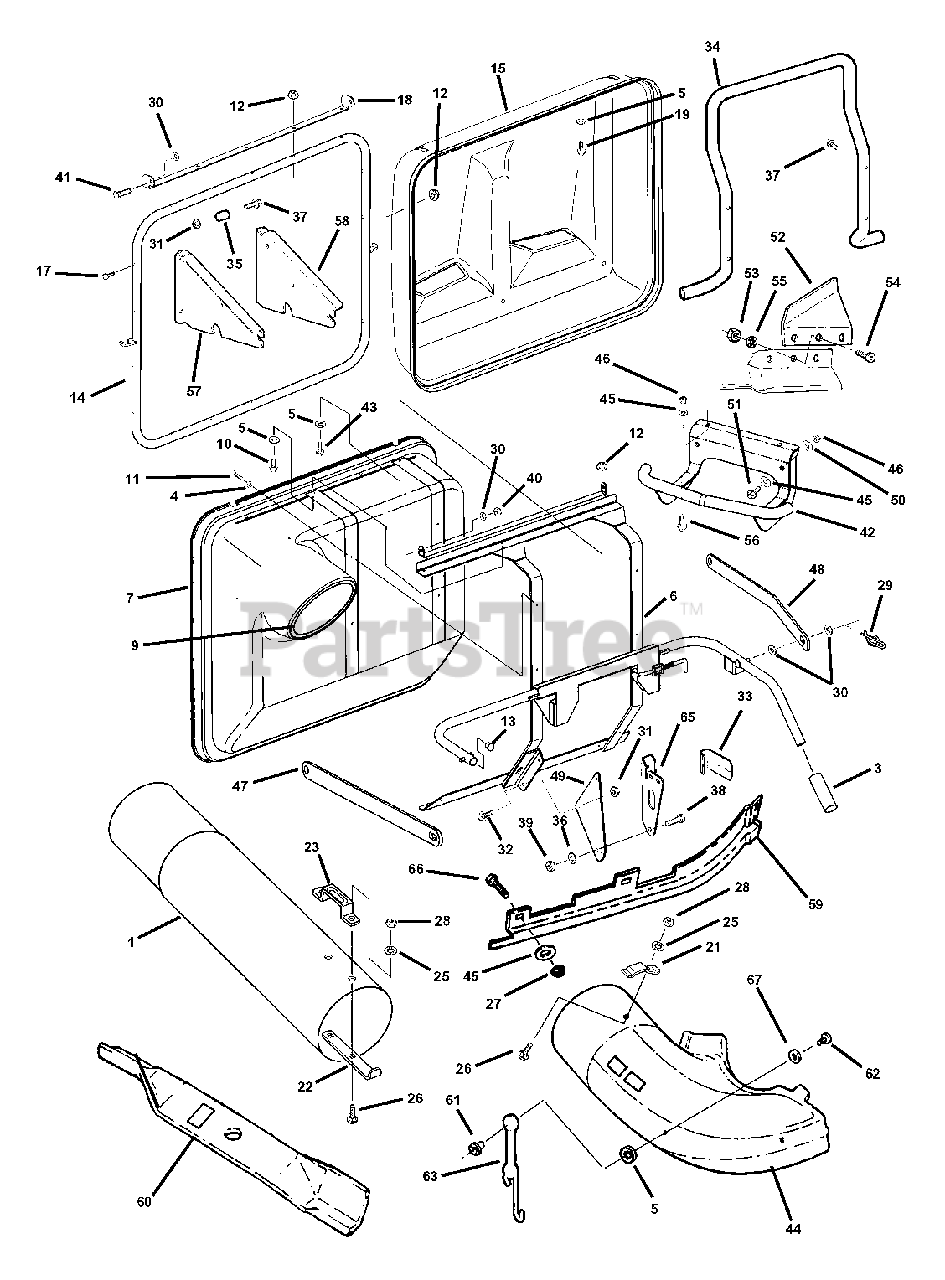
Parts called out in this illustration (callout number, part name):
1	TUBE, Grass
3	GRIP
4	WASHER, 11/32 Flat
5	WASHER, 3/16 Flat
6	WELDMENT, Front Cover Brace
7	COVER, Front
9	GASKET, Chute
10	SCREW, #10-24 x 1/2" Hex Washer Self-Tap (Torx)
11	SCREW, 1/4-20 x 5/8" Pan Head Self-Tapping
12	NUT, #10-24 Hex Fl. Lock
13	END CAP, Tube
14	WELDMENT, Rear Cover Brace
15	COVER, Rear
17	BOLT, #10-24 x 1-1/2" Oval Head
18	HINGE, Rear Cover
19	SCREW, #10-24 x 1-1/2 Machine
21	LATCH, Chute/Tube
22	BASE, Handle
23	HANDLE, Tube
25	WASHER, 1/4 Internal Tooth Lock
26	BOLT, 1/4-20 x 3/4" Round Hd. Short Nk. Carriage, Gr. 5
27	NUT, 5/16-18 Hex Ctr. Lock
28	NUT, 1/4-20 Hex
29	PIN, 3/8 Self Lock Cotter
30	WASHER, 3/8" Flat
31	NUT, 5/16-18 Flange Lock
32	BOLT, 5/16-18 x 5/8" Hex Flange Lock
33	SUPPORT, Bumper
34	BUMPER, Rear
35	SPACER, Bumper Bracket
36	WASHER, 1/2 Internal Tooth Lock
37	SCREW, 5/16-18 x 1-3/4" Hex Washer Self-Tapping
38	BOLT, 1/2-13 x 1" Hex Head Cap Grade 5
39	NUT, 1/2-13 Hex Grade B
40	NUT, 3/8-16 Hex Lock
41	SCREW, 3/8-16 x 1" Hex Head Cap, Grade 5
42	WELDMENT, LT Bumper
43	BOLT, #10-24 x 3/4" Hex Flange Lock, Grade 5
44	ASSEMBLY, Chute
45	WASHER, 5/16" Flat
46	NUT, 5/16-18 Hex Nyloc
47	LINK, Handle (Right Hand)
48	LINK, Handle (Left Hand)
49	PLATE, Hitch
50	WASHER, 7/16" Flat
51	BOLT, 3/8-16 x 1" Hex Flange Lock
52	Air Lift
53	NUT, 5/16-24 Hex
54	SCREW, 5/16-24 x 5/8" Oval Head Machine
55	WASHER, 5/16 Internal Tooth Lock
56	BOLT, 5/16-18 x 7/8" Hex Flange Lock
57	BRACKET, Bumper Support (Right Hand)
58	BRACKET, Bumper Support (Left Hand)
59	BAFFLE, 38 Deck MY 97
60	ASS'Y, Air Lift Blade
61	NUT, Weld- 10/24 Thread
62	SCREW, 10/24 x 5/8" Pan Head
63	STRAP, Bag Adap./Tube
65	BRACE, Bumper
66	SCREW, 5/16-18 x 3/4" Hex Head Cap, Grade 5
67	WASHER, .219 I.D. Flat
